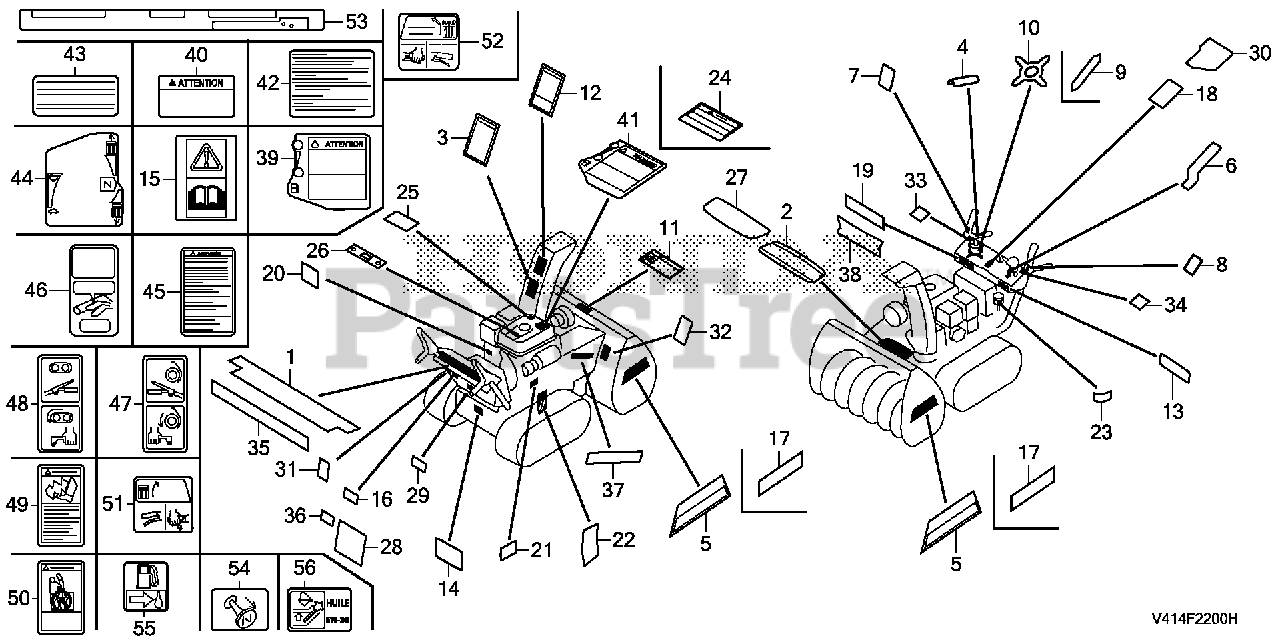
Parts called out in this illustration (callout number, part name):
1	LABEL, OPERATION (ENGLISH)
3	LABEL, WARNING (ENGLISH)
5	MARK, STRIPE
6	MARK, CHANGE INDICATION
7	MARK, AUGER CLUTCH (ENGLISH)
8	MARK, CLUTCH (ENGLISH)
9	MARK, CHUTE CONTROL OPERATION (ENGLISH)
11	MARK, HOUSING DANGER (ENGLISH)
12	MARK, DISCHARGE DANGER (ENGLISH)
13	MARK (H.S.T.)
14	MARK, INDICATION (H.S.T.)(ENGLISH)
16	MARK, CHOKE INDICATION (ENGLISH)
18	MARK, THROTTLE (ENGLISH)
19	MARK B, HONDA
20	MARK, FUEL INDICATION (ENGLISH)
21	MARK, OIL CAUTION (ENGLISH)
22	MARK, HEIGHT ADJUSTING
23	LABEL, OIL RECOMMENDATION (ENGLISH)
